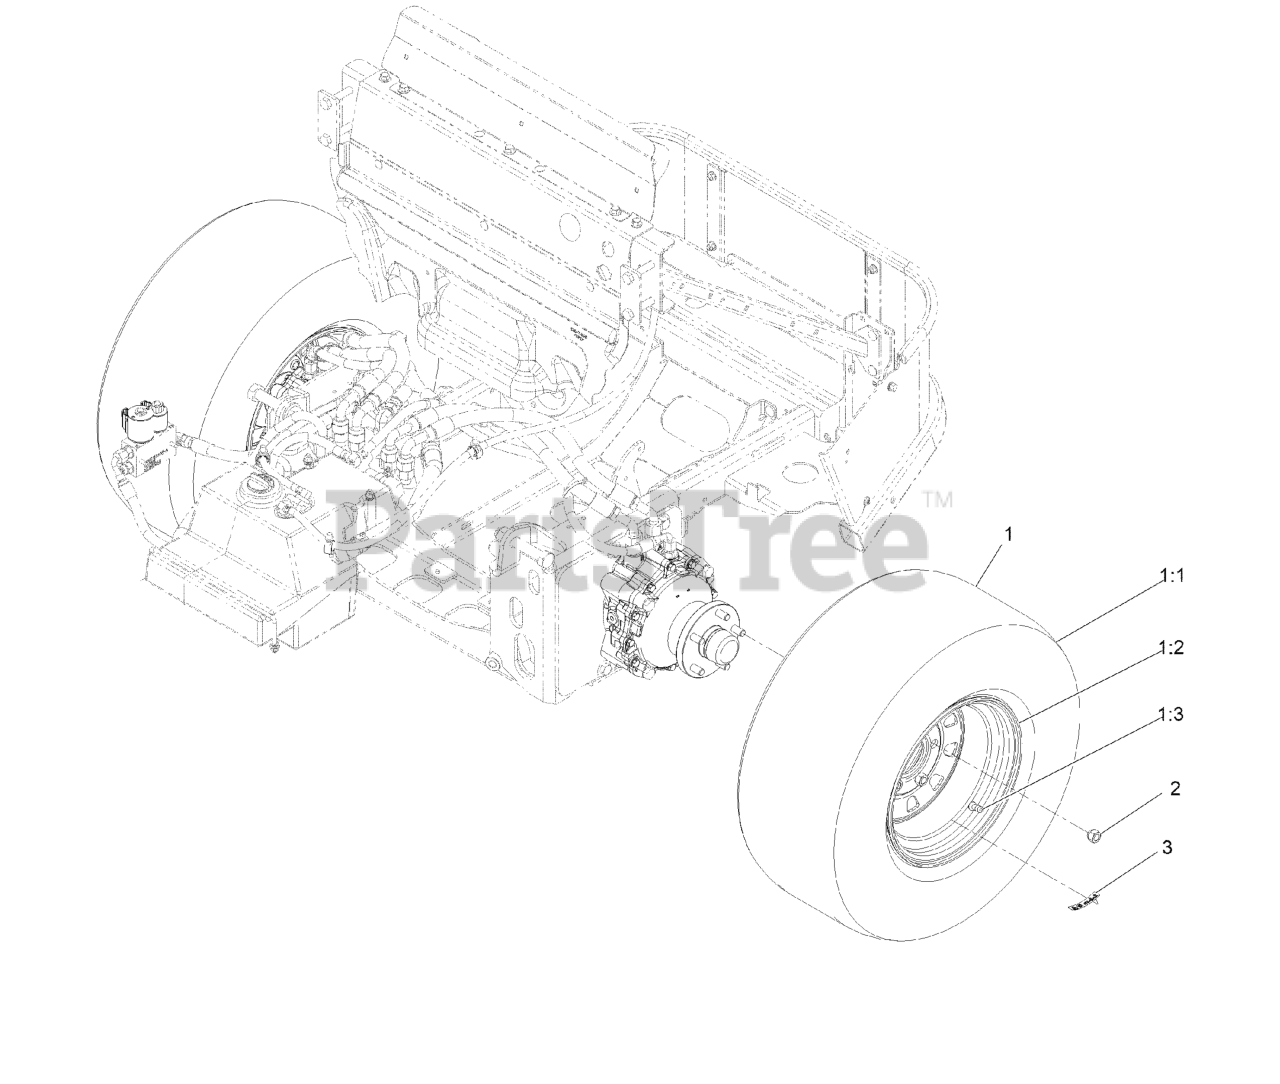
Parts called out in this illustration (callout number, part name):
1	ASM-TIRE 26 X 12-12
1:1	RIM ASM
1:3	Stem-Valve
2	NUT-LUG
3	DECAL-TORQUE, WHEEL NUT
